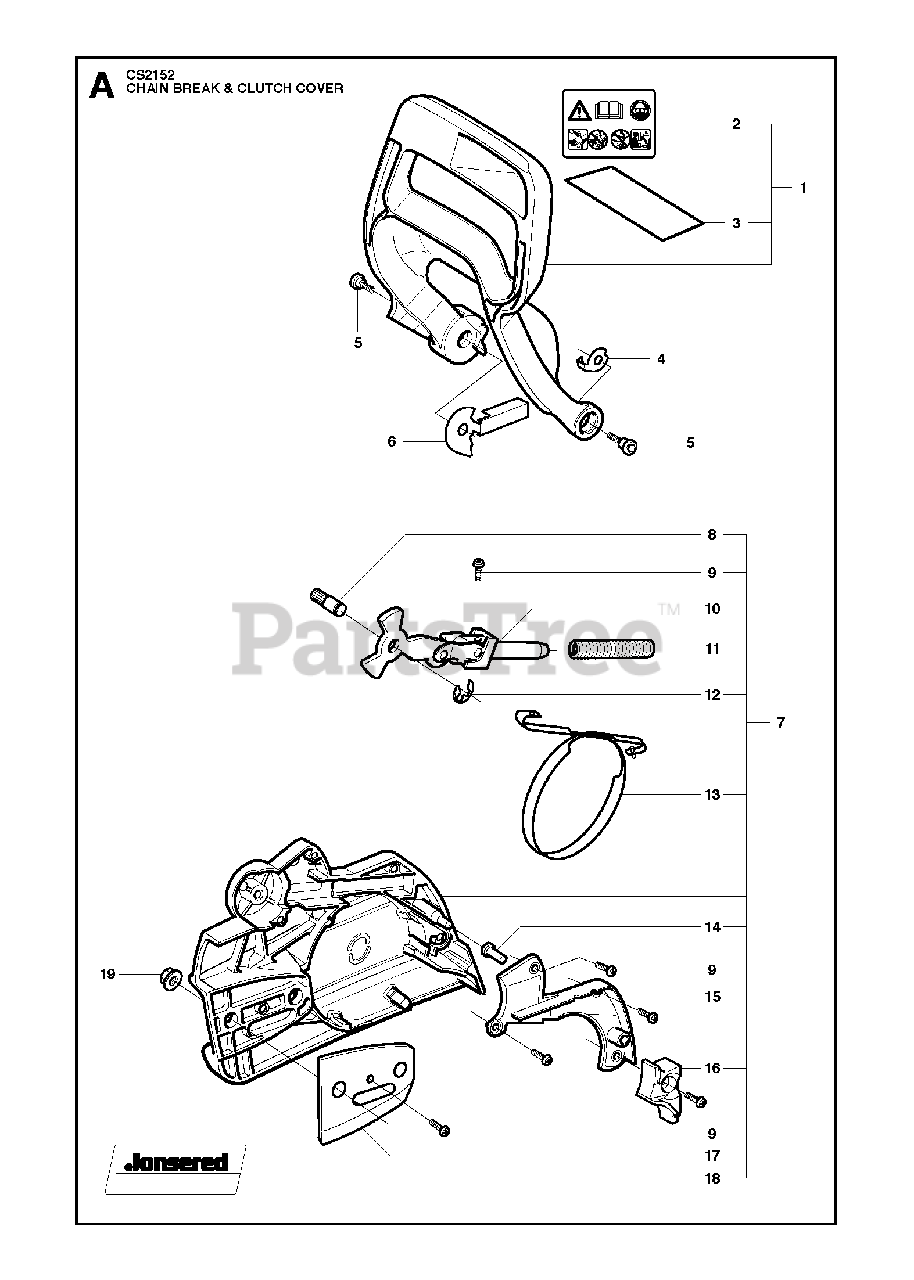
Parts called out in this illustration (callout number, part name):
1	HAND GUARD
2	DECAL
3	PROTECTOR
6	PROTECTOR
7	CHAIN BRAKE
8	PIN
9	SCREW
10	JOINT
11	SPRING
12	E-RING 4
13	BRAKE BAND
14	SLEEVE
15	COVER
16	PROTECTOR
17	PLATE
18	DECAL
19	NUT M8 FLANGE
